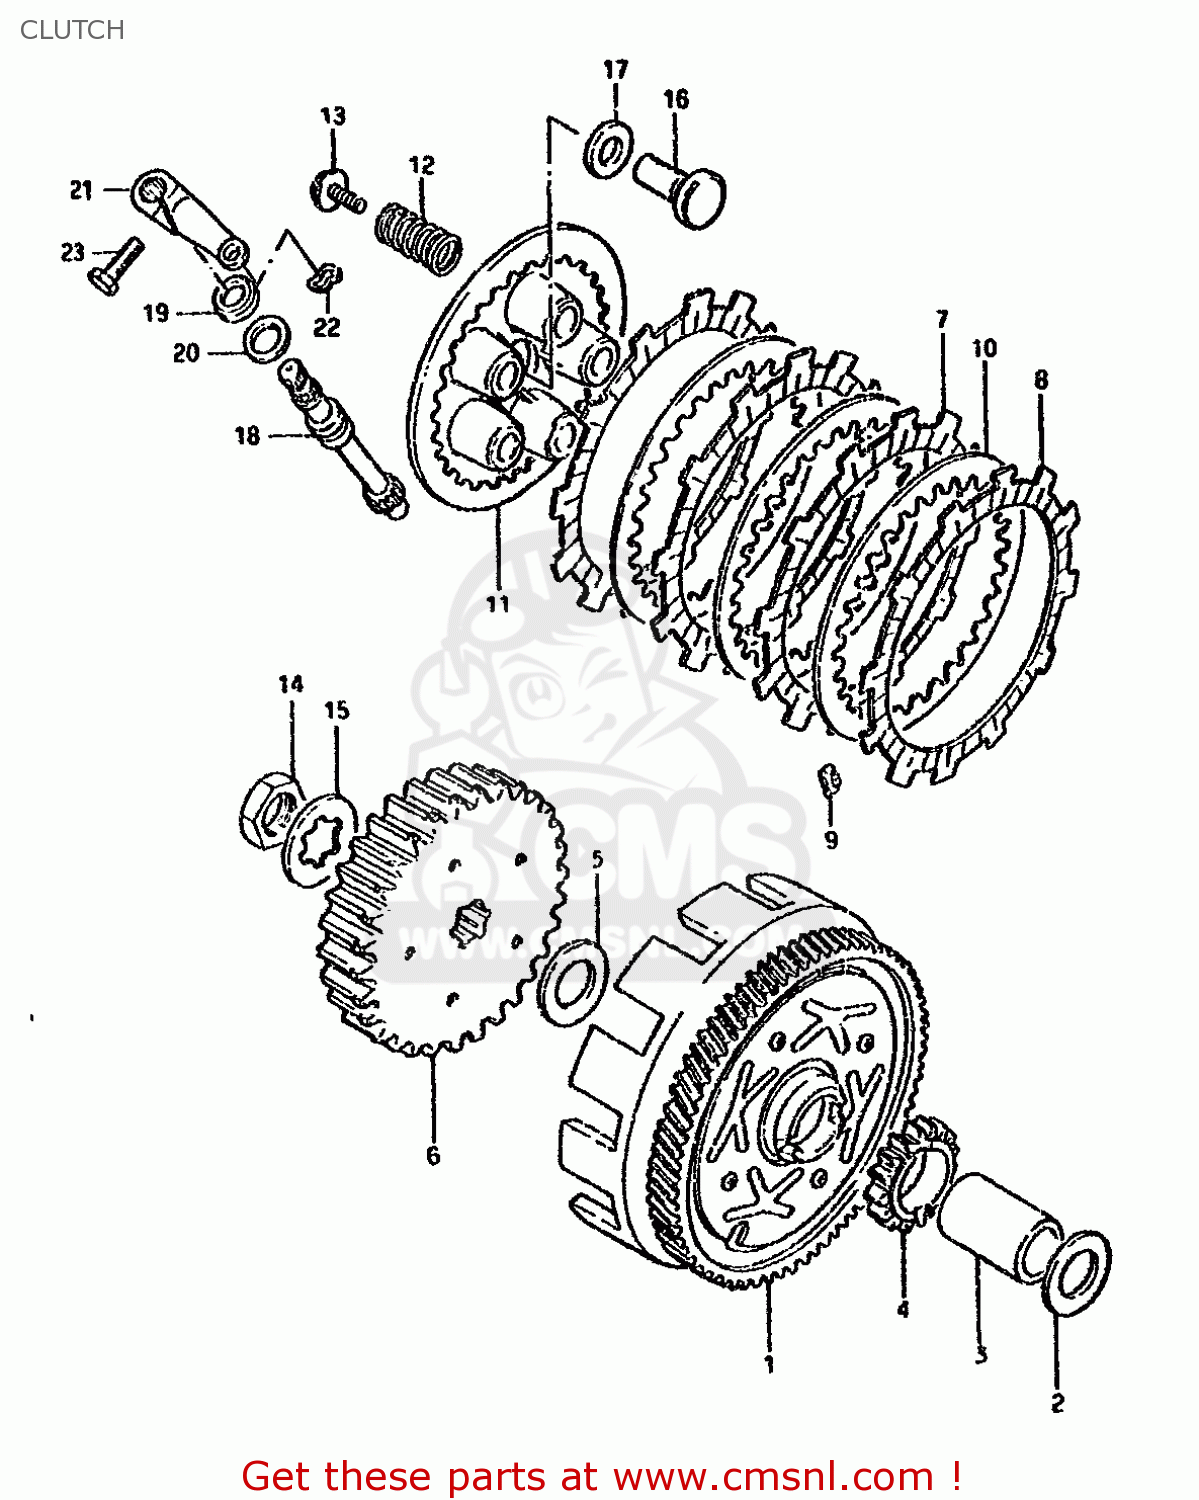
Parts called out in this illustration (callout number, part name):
1	GEAR ASSY,PRI DRIVEN(NT:73)
2	WASHER,THRUST
3	SPACER
4	GEAR,KICK STARTER DRIVE
5	WASHER
6	HUB,CLUTCH SLEEVE
7	PLATE,CLUTCH DRIVE (NAS)
8	PLATE,CLUTCH DRIVE (NAS)
9	DAMPER
10	PLATE,CLUTCH DRIVEN (NAS)
11	DISC,CLUTCH PRESSURE
12	SPRING
13	BOLT 5X16
14	NUT
15	WASHER,LOCK
16	RACK,CLUTCH RELEASE
17	BEARING(10X22X2.8)
18	PINION,CLUTCH RELEASE
19	SEAL,OIL(10X17X5)
20	WASHER
21	ARM,CLUTCH RELEASE
22	WASHER
23	BOLT
